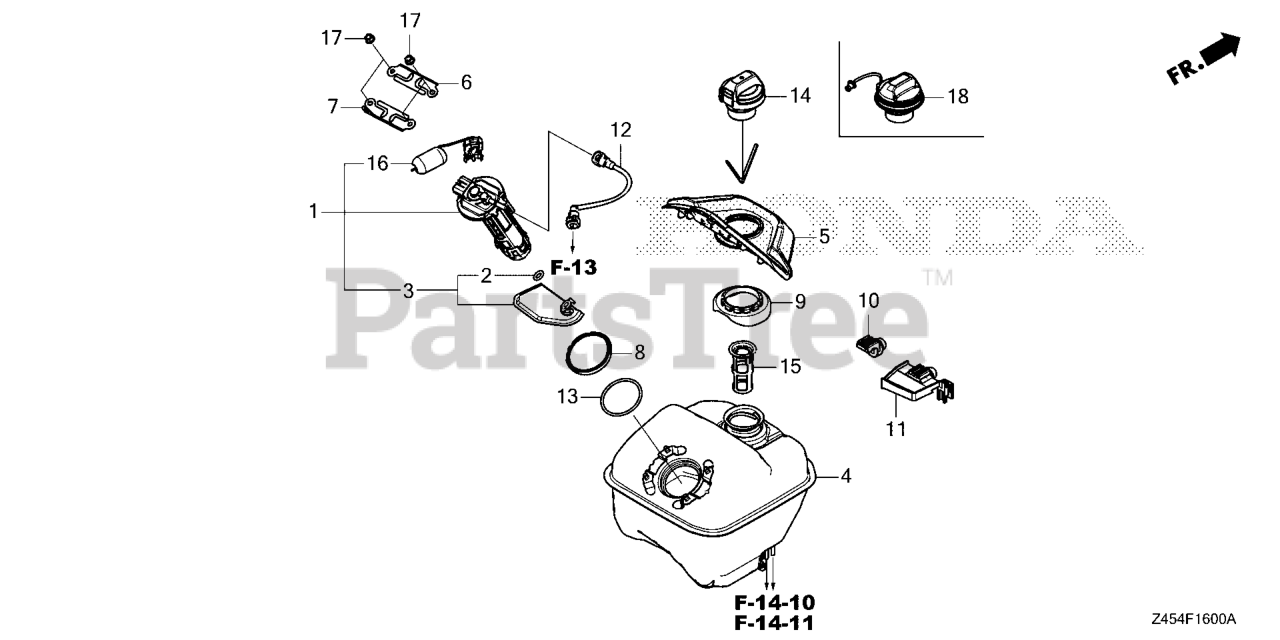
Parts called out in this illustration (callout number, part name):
1	UNIT, FUEL PUMP
2	O-RING (6.8X1.9)
3	FILTER SET
4	TANK COMP, FUEL
6	RETAINER, FUEL PUMP
7	RETAINER, FUEL PUMP
8	DUST SEAL (OHTUKA POLY-TECH)
9	RUBBER, FUEL FILLER
10	RUBBER A, TANK MT
11	RUBBER B, TANK MT
12	HOSE COMP, FUEL FEED
13	O-RING, FUEL PUMP
15	FILTER COMP, FUEL
17	NUT, FLANGE (6MM)
